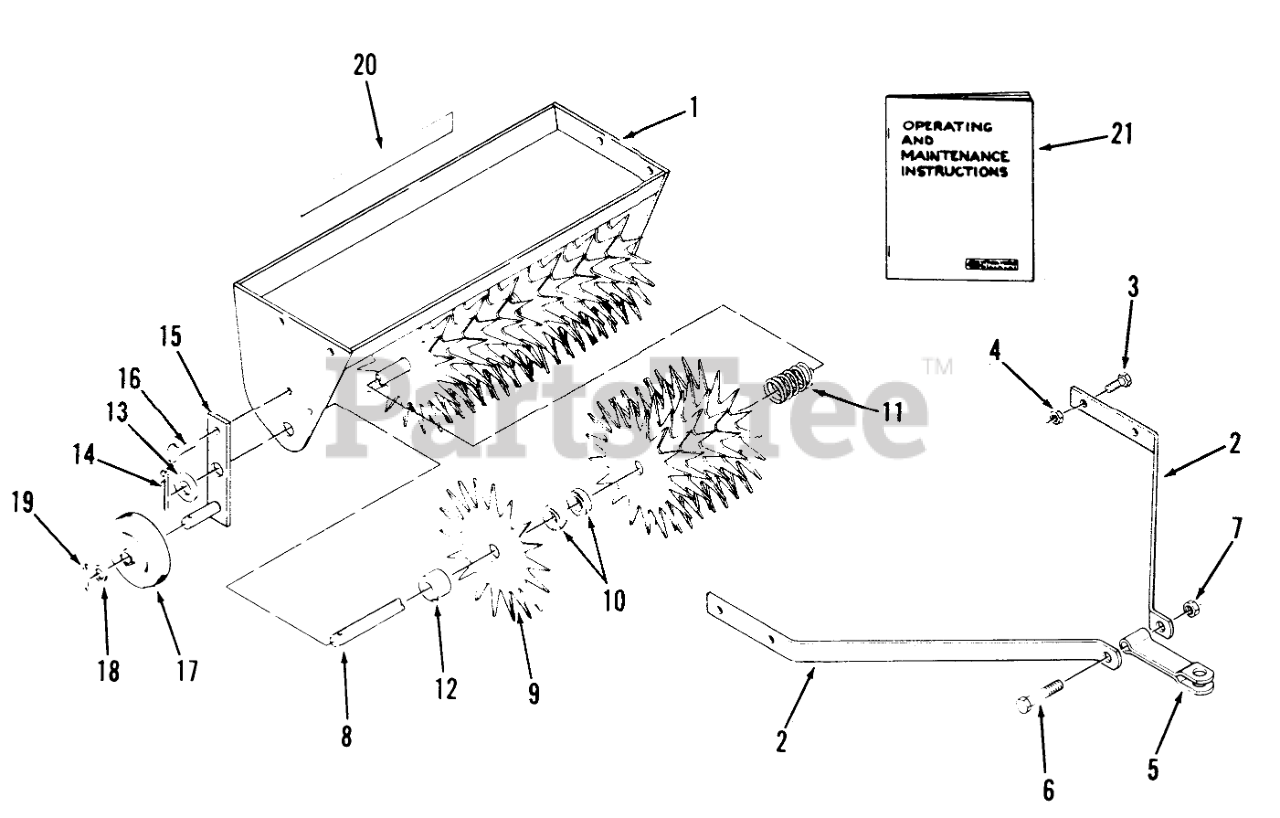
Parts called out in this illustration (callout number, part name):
1	Weight Tray Assembly
2	Side Bar
3	Bolt
4	Nut
5	Hitch Assembly
6	Bolt 1/2-13 x 3 1/2
7	Nut
9	Spike
10	Cup Spacer
11	Spring
12	BUSHING
13	Washer
14	Cotter Pin
15	R.H. Wheel Holder
16	Thumb Screw
17	Wheel
18	Washer
19	Cotter Pin
20	DECAL-WHEEL HORSE
21	Operating and Maintenance Instructions
